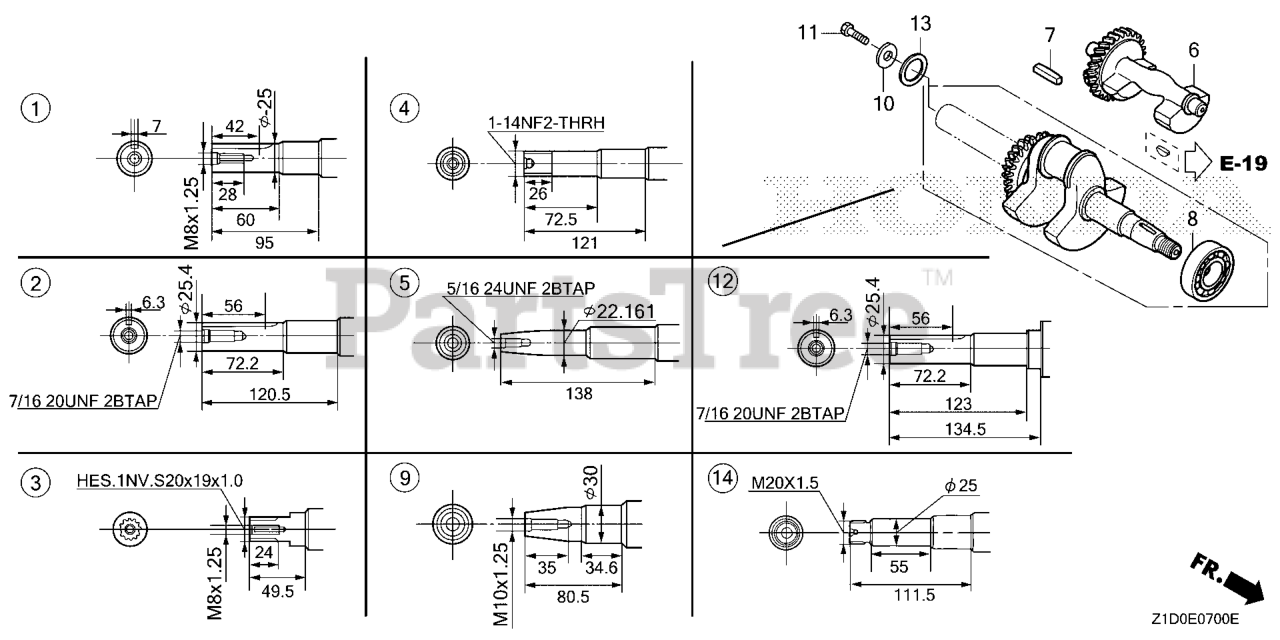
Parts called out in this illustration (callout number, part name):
2	CRANKSHAFT
7	KEY (6.3X6.3X43)
8	BEARING, RADIAL BALL (6206 SH)
